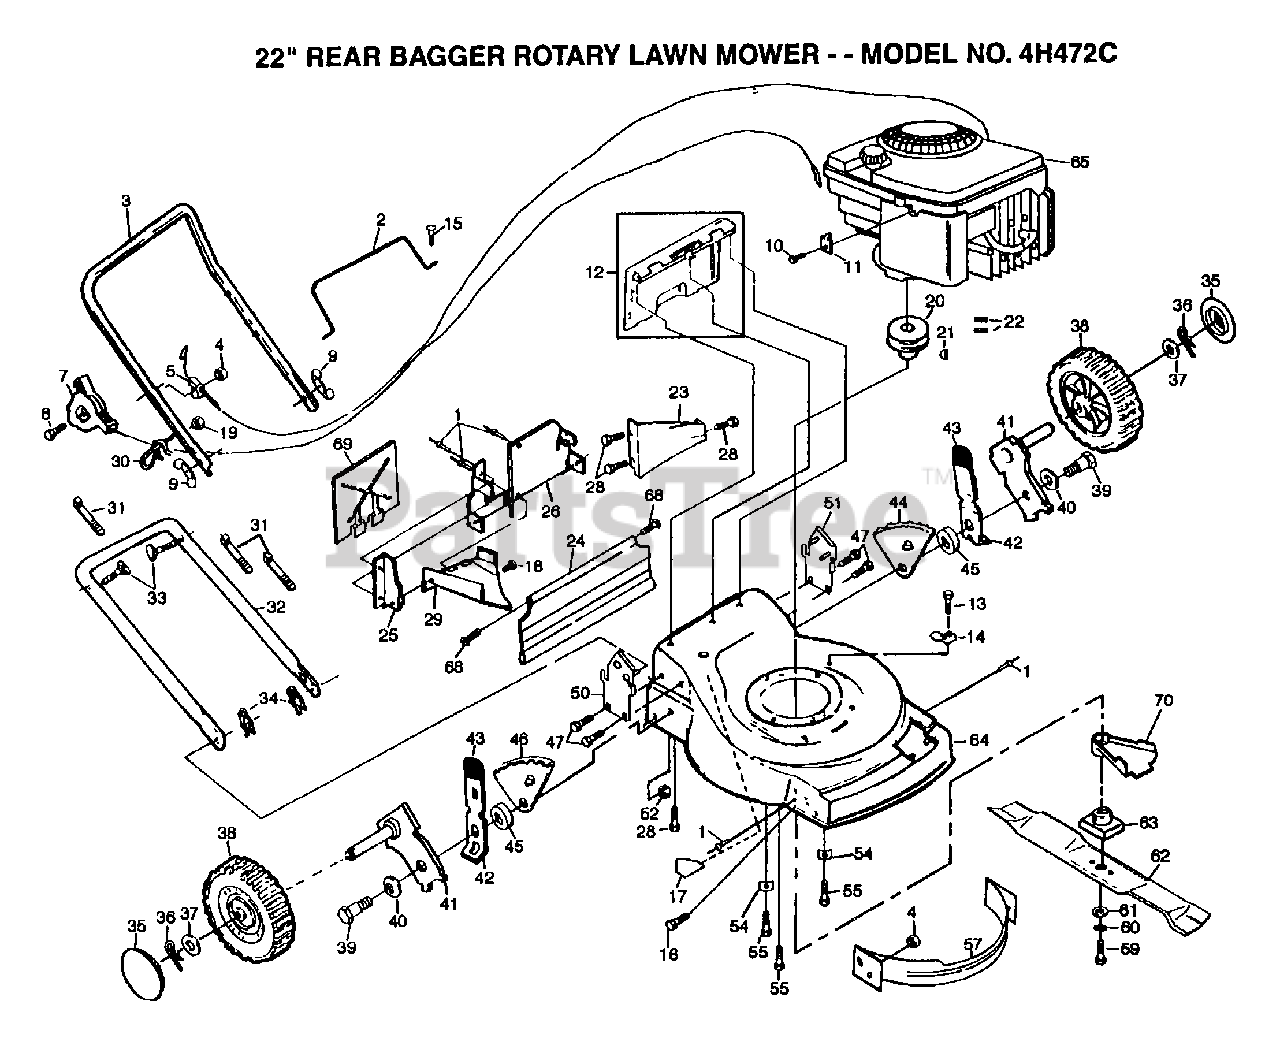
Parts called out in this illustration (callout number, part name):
1	BLIND RIVET
2	CONTROL BAR
5	"CABLE,ENG ZONE CO"
7	"CONTROL, THROTTLE"
8	SCREW.HXHD.WASH.
9	"NUT,WING PM"
10	SCREW PM
11	CABLE CLAMP
13	TAPPING SCREW
14	GUIDE CLIP PM
15	"SCREW,PAN HD"
16	SCREW
17	DECAL HYT
18	SCREW PM
19	NUT
20	ENGINE.PULLEY.FWG
21	HI PRO KEY PM
22	SCREW
23	REAR BAFFLE
24	SKIRT.REAR.FGD.22
26	PLATE.BACK.22RD
28	SCREW
29	DISCHARGE BAFFLE
30	ROPE GUIDE
33	BOLT.HANDLE.LM
34	HAIRPIN COTTER
35	HUB CAP
36	RETAINER CLIP PM
37	WASHER
39	BOLT SHLD 3/8-16
40	"WASHER, BELLEVIL."
41	AXLE ARM
42	SPRING SELECTOR
43	KNOB PM
44	BRACKET.ADJ.9.LH
46	BRACKET.ADJ.9.RH
47	SCREW
52	LOCKNUT PM
55	SCREW
59	SCREW
60	LOCKWASHER
61	"WASHER,HARDEN"
62	"BLADE.MULCH.22"""
63	ADAPTOR.BLADE.LM
64	KIT.HSG.22RD.FWGD
68	HINGE SCREW
69	MULCHER PLATE
